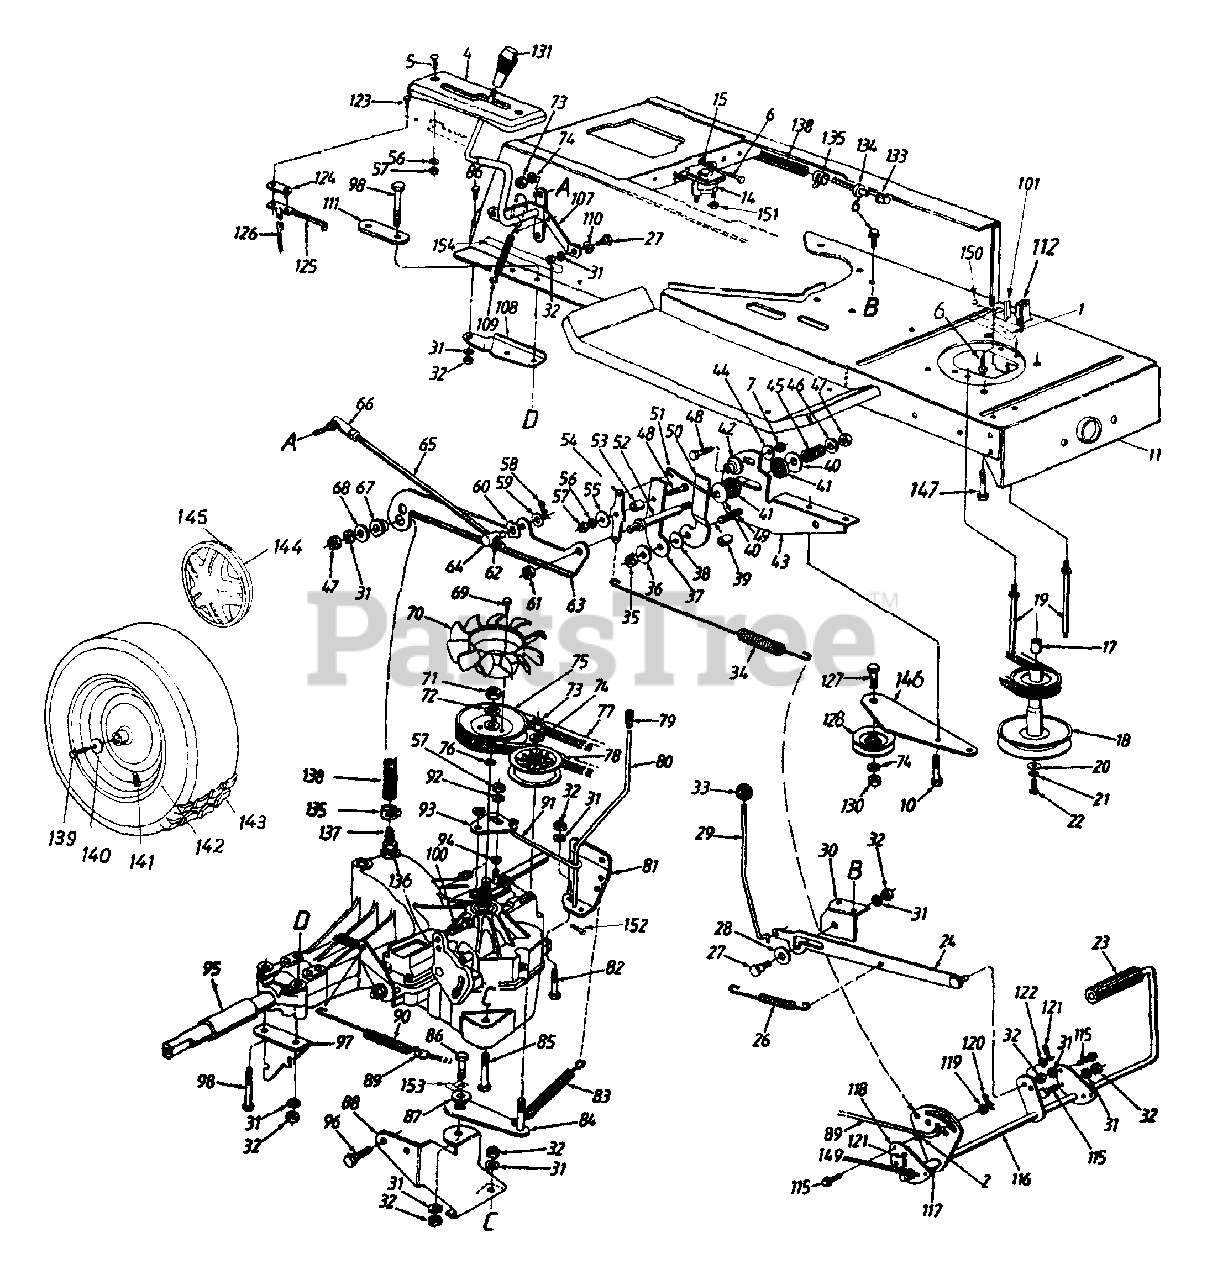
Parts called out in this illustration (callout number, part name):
1	Spring Switch
2	Hex Sems Nut 5/16-18 Thd.
4	Index Bracket
5	Pan Hd. Mach. Scr. 1/4-20 x .75"
6	Hex Wash. Hd. TT-Tap Scr.
7	Hex Nut 1/4-28 Thd.
8	L-Wash. 1/4" I.D.
10	Hex. Bolt 1/4-28 x .62" Lg.
11	Lower Frame Ass'y.
14	Solenoid
15	Ext. L-Wash. 1/4" I.D.
17	Spacer
18	Engine Pulley
19	Belt Guard Stud 4.75" Lg.
20	Fl-Wash. 7/16" I.D. x 1.25" O.D.
21	L-Wash. 7/16" I.D.
22	Hex Bolt 7/16-20 x 1.25" Lg.
23	Foot Pad
24	Brake Lockout Brkt. Ass'y.
26	Foot Pedal Return Spring
27	Shld. Bolt .437" Dia. x .268"
28	Fl-Wash. 7/16" I.D. x 1-3/8" O.D.
29	Lock-up Rod
30	Bracket
31	L-Wash. 5/16" I.D.
32	Hex Nut 5/16-18 Thd.
33	Ball Knob
34	Neutral Return Spring
35	Hex Nut 5/16-24 Thd.
36	Fl-Wash. .344" I.D. x 1" O.D.
37	Scissor-Flat
38	Fl-Wash. .33" I.D. x 1.25" O.D.
39	Spacer
40	Bell-Wash. .4" I.D. x 1.13" O.D.
41	Friction Washer
42	Centering Gauge Spacer
43	Neutral Return Mtg. Brkt.
44	Bell-Wash. .265" I.D. x .75" O.D.
45	Comp. Spring 1.19" Lg.
46	Fl-Wash. .26" I.D. x .72" O.D.
47	Hex Nut 5/16-24 Thd.
48	Hex Bolt 1/4-28 x 1" Lg. (Gr. 5)
49	Rib Neck Bolt 5/16-24 x .84" Lg.
50	Scissor-Offset
51	Neutral Return Rod
52	Friction Disc Stud
53	Shld. Spacer
54	Neutral Return Lever
55	Fl-Wash. .265" I.D. x 1" O.D.
56	L-Wash. 1/4" I.D.
57	Hex Nut 1/4-20 Thd.
58	Hairpin Clip
59	Fl-Wash. .375" I.D. x .87" O.D.
60	Spring Wash. .39" I.D.
61	Hex L-Nut 3/8-24 Thd.
62	Hex Jam Nut 3/8-24 Thd.
63	Neutral Return Brkt.
64	Ferrule 3/8-24 Thd.
65	Control Rod
66	Ball Joint 3/8-24 Thd.
67	Shld. Spacer.5" Dia. x .27" Lg.
68	Fl-Wash. .349" I.D. x .879" O.D.
69	Hex Tap Scr. #12 x .62" Lg.
71	Hex Nut 1/2-20 Thd.
72	L-Wash. 1/2" I.D.
73	Hex Nut 3/8-24 Thd.
74	L-Wash. 3/8" I.D.
75	Transmission Pulley
76	Wire Ring
77	V-Belt 1/2 x 77
77	V-Belt Type A x 76.1
78	Fl-Idler Pulley 2.75" O.D.
79	Rod End Grip
80	Bypass Control Lever
81	Transaxle Support Brkt. - L.H.
82	Hex Bolt 5/16-18 x 1.25" Lg.
83	Ext. Spring 6.12
86	Hex Bolt 5/16 x 3/4
87	Shld. Spacer .5" Dia. x .27" Lg.
88	Transaxle Support Brkt. - R.H.
89	Brake Rod 24.94" Lg.
90	Ext. Spring
91	Bypass Actuator Rod
92	Fl-Wash. .281" I.D. x .5" O.D.
93	Bypass Adjustment Brkt.
94	External L-Wash. 1/4" I.D.
95	Sleeve .758" I.D. x 1" O.D.
96	Hex. TT-Tap Scr. 5/16-18 x .62"
97	Retainer Brkt. - Transaxle
98	Hex Bolt 5/16-18 x 2.75" Lg.
98	Hex Bolt 5/16-18 x 4.5" Lg.
99	Tension Spring
100	Hex Bolt 5/16-24 x 1" Lg.
101	Hex Wash. Hd. AB-Tap Scr.
107	Speed Control Lever Ass'y.
108	Axle Support Brkt. - R.H.
108	Axle Support Brkt. - L.H.
109	Ext. Spring 2.75" Lg.
110	Spr-Wash. .445" I.D. x .75" O.D.
111	Transaxle Mtg. Brkt.
112	Safety Switch (Clutch)
115	Hex TT-Tap Scr. 5/16-18 x 7/8"
116	Clutch/Brake Pedal Ass'y.
117	Spacer .63" I.D.
118	Pedal Bracket
119	Fl-Wash. .344" I.D. x .75" O.D.
120	Cotter Pin 3/32" Dia.
121	Cotter Pin 1/8" Dia.
122	Fl-Wash. .385" I.D. x .62" O.D.
123	Hex AB-Tap Scr. #8 x .5" Lg.
124	Insulator Nut Plate
125	Reverse Safety Switch
126	Extension Wire
127	Hex Bolt 3/8-16 x 1.5" Lg.
128	Idler Pulley
129	Fl-Wash. .39" I.D.
130	Hex Nut 3/8-16 Thd.
131	Shift Knob
133	Vent Cap
134	Plastic Vent
135	Clamp
136	O-Ring
137	Hose Fitting
138	Fuel Line 18" Lg.
139	Hex Bolt 5/16-24 x .75" Lg.
140	Bell-Wash. .345" I.D. x .88" O.D.
141	Air Valve
144	Hub Cap (Gray)
144	Hub Cap (Beige)
144	Hub Cap (Yellow)
145	Spring Clip
146	Idler Bracket
147	Hex TT-Tap Scr. 3/8-16 x 1.25"
148	Spacer .32" I.D. x.75" O.D.
149	Lock Washer 3/8
150	Hex Washer Screw #10 -16 x .5
151	Nut 1/4-20
152	Cotter Pin 1/16 x .75
153	Clamp
154	Reinforcement Speed Control Bracket
